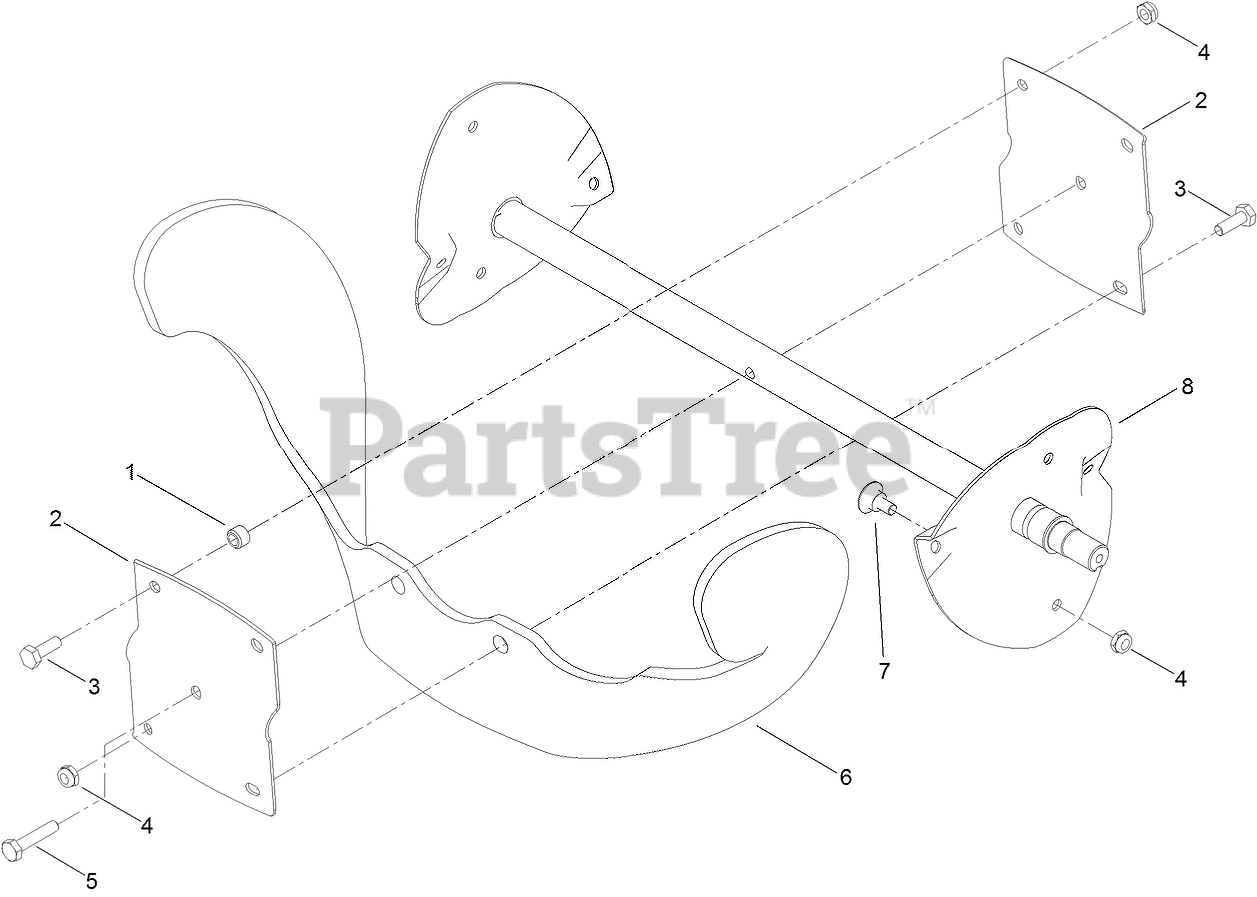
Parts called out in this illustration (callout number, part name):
1	SPACER-BLADE, ROTOR
2	HALF-ROTOR
3	SCREW-HH
4	NUT-LOCK, NI
5	SCREW-HH
6	BLADE-ROTOR
7	SCREW
8	ROTOR
